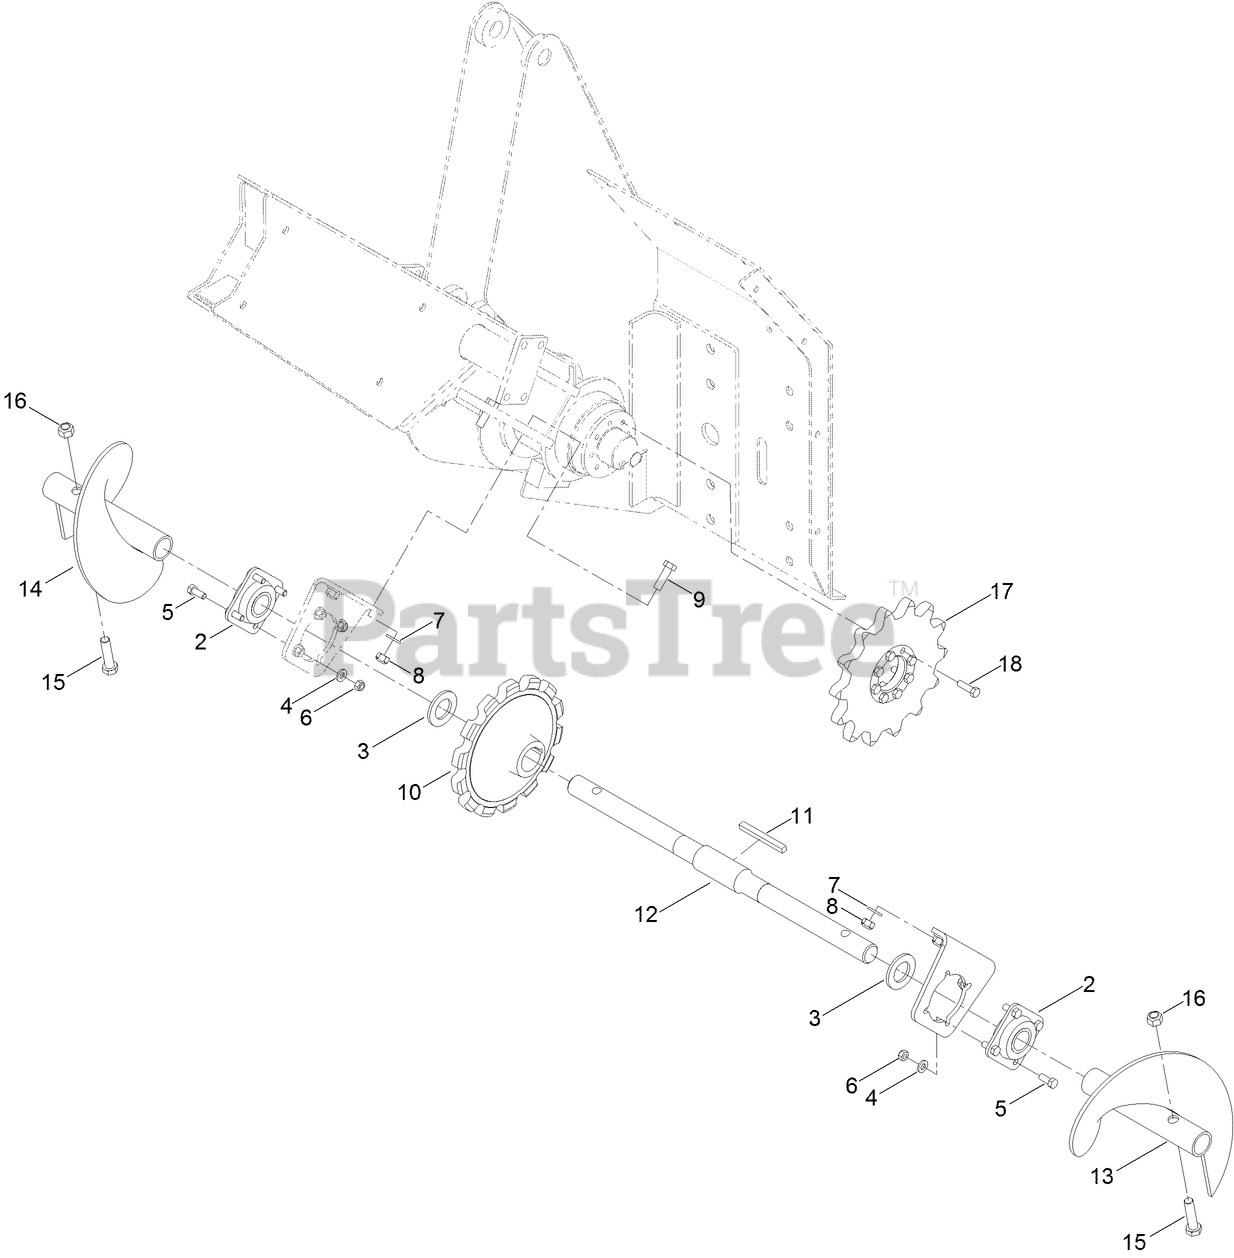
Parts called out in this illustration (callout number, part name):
2	BEARING
5	SCREW-HH
6	LOCKNUT
7	WASHER-FLAT
8	NUT-CROWNLOCK
9	SCREW-HH
10	SPROCKET-AUGER, 14T
11	KEY-SQUARE
12	SHAFT-auger
15	SCREW-HH
16	NUT-LOCK
17	SPROCKET-14 TEETH
18	SCREW-HH
